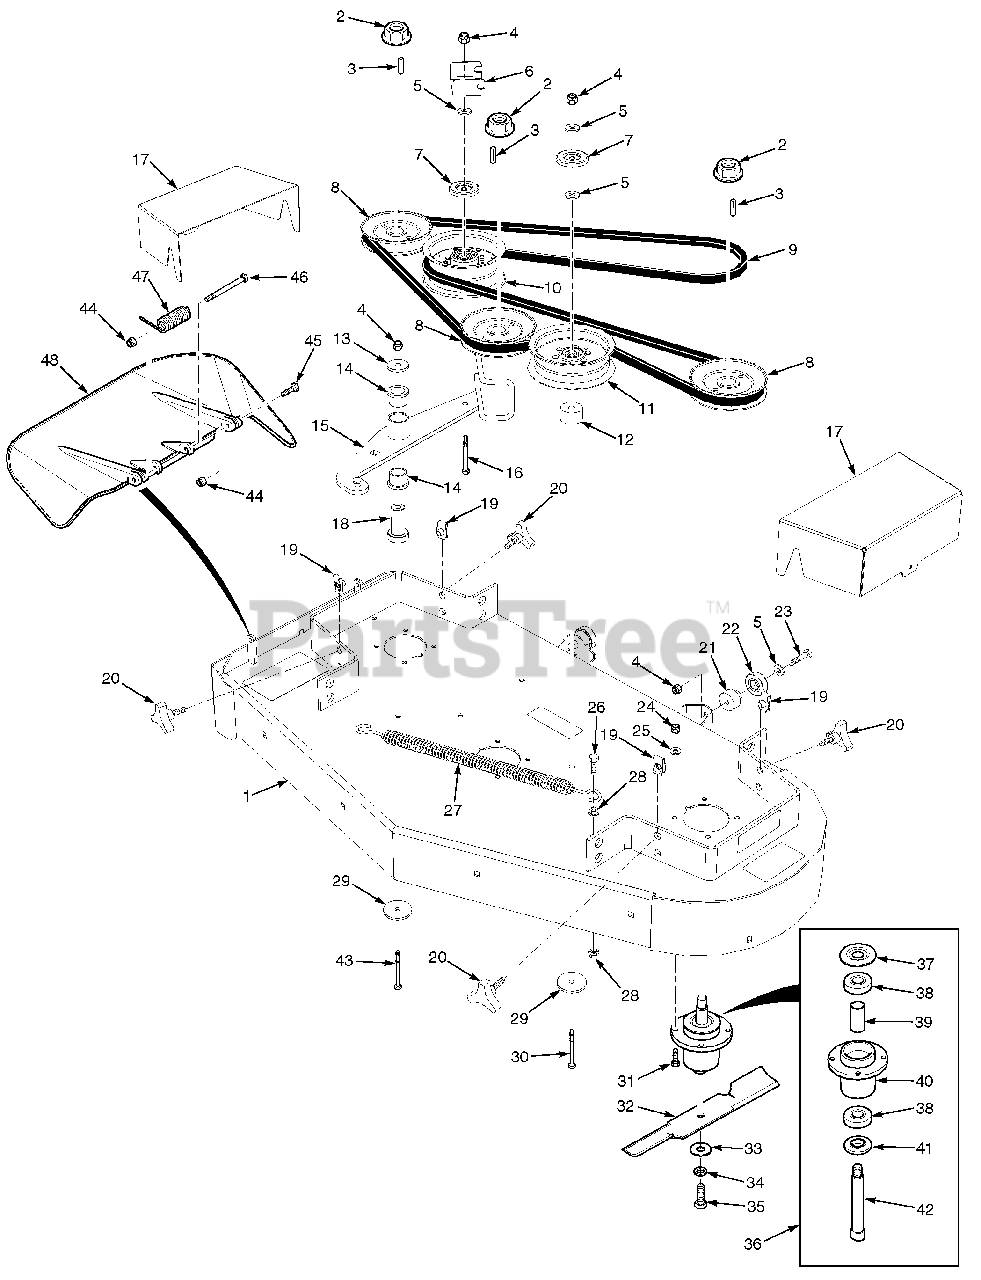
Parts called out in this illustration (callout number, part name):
1	Cutter Deck Weldment w/Decals
2	Nut, 3/4-16 Spiral Lock
3	Key, 1/4 x 1/4 x 1-1/4"
4	Nut, Elastic Stop 3/8-16
5	Flatwasher, 3/8-.391 x .938 x .105 HD
6	Bracket, Belt Guide
7	Dust Shield
8	Pulley, 5.13" Dia.
9	Belt, Cutter Deck
10	Pulley, 5" Idler
11	Pulley, 5" Idler
12	Spacer, Idler Pulley
13	Flatwasher, 3/8-.406 x 1-1/2"
14	Bearing
15	Idler Arm Assembly
16	Bolt, Hex Head 3/8-16 x 3-1/4"
17	Belt Cover, SFW 48
18	Pivot, Idler
19	U-Nut, 3/8-16
20	Knob, w/Stud
21	Spacer, Bearing
22	Bearing
23	Bolt, Hex Head 3/8-16 x 2-1/4"
24	Nut, Elastic Stop 5/16-18
25	Lockwasher, 5/16" Spring
26	Bolt, Hex Head 3/8-16 x 1-1/2" Gr.8
27	Spring, Deck Idler
28	Nut, Serrated Flange 3/8-16
29	Flatwasher, 3/8-.406 x 2-1/4 x .187
30	Bolt, Hex Head 3/8-16 x 3-1/2"
31	Bolt, Hex Head 5/16-18 x 1-1/2" Gr.8
32	Cutter Blade, 16-1/2"
33	Flatwasher, 5/8-.688 x 1-3/4 x .134 HD
34	Lockwasher, 1/2" Spring
35	Bolt, Hex Head 5/8-11 x 1-1/2"
36	Spindle Assembly
37	Debris Shield
38	Bearing
39	Spacer, Bearing
40	Spindle Housing Assembly
41	Protector, Bearing
42	Shaft, Spindle
43	Bolt, Hex Head 3/8-16 x 3-3/4"
44	Nut, Elastic Stop 5/16-18
45	Bolt, Hex Head 5/16-18 x 1-3/4"
46	Bolt, Hex Head 5/16-18 x 4-3/4"
47	Spring, Discharge Chute
48	Discharge Chute Assembly
